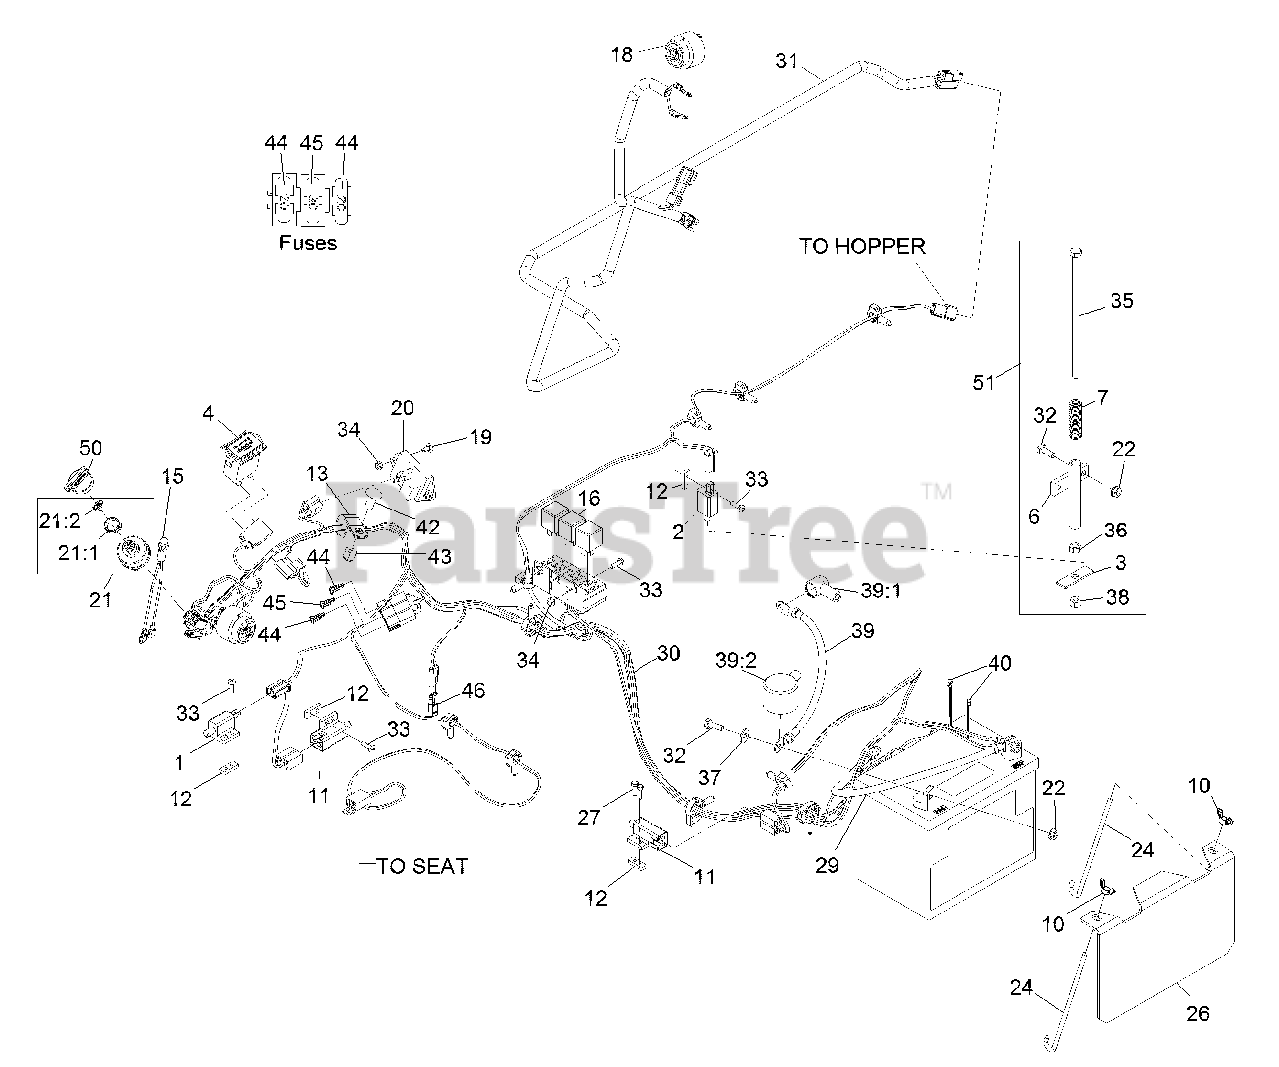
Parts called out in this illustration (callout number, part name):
1	SWITCH-OPEN, NORMALLY
2	SWITCH-CLOSED, NORMALLY
3	PLATE-SWITCH, SEAT
4	METER-HOUR
6	MOUNT-SPRING, SEAT
7	SPRING-SWITCH, SEAT
10	WINGNUT
12	PLATE-TAPPED
13	CLIP-LOOM
15	INDICATOR-LED, RED
18	ALARM-TONE, DUAL
19	BOLT-CARR
20	MODULE-DELAY, SEAT
21	ASM,SWITCH W/NUT
21:1	NUT-SWITCH, IGNITION
21:2	KEYS-IGNITION (SPARE PAIR
24	BOLT-HOLDDOWN
26	HOLD DOWN-BATTERY
29	CABLE-BATTERY, NEGATIVE
30	HARNESS-WIRING NAVIGATOR
31	HARNESS-WIRE, HOPPER
32	SCREW-HH
33	SCREW-PPH
34	NUT-LOCK, NI
35	SCREW-HH
36	NUT-HEX
37	WASHER-FLAT
38	NUT-LOCK, NI
39	CABLE-BATTERY, POSITIVE
39:1	INSULATOR-SOLENOID
39:2	INSULATOR-BATTERY
40	TIE-CABLE
42	SCREW-CARR
43	NUT-LOCK, NI
44	FUSE-BLADE TYPE, 20 AMP
45	FUSE-BLADE TYPE, 30 AMP
46	CAP-PLUG
50	KEY-IGNITION
51	HOPPER SWITCH ACTUATOR AS
